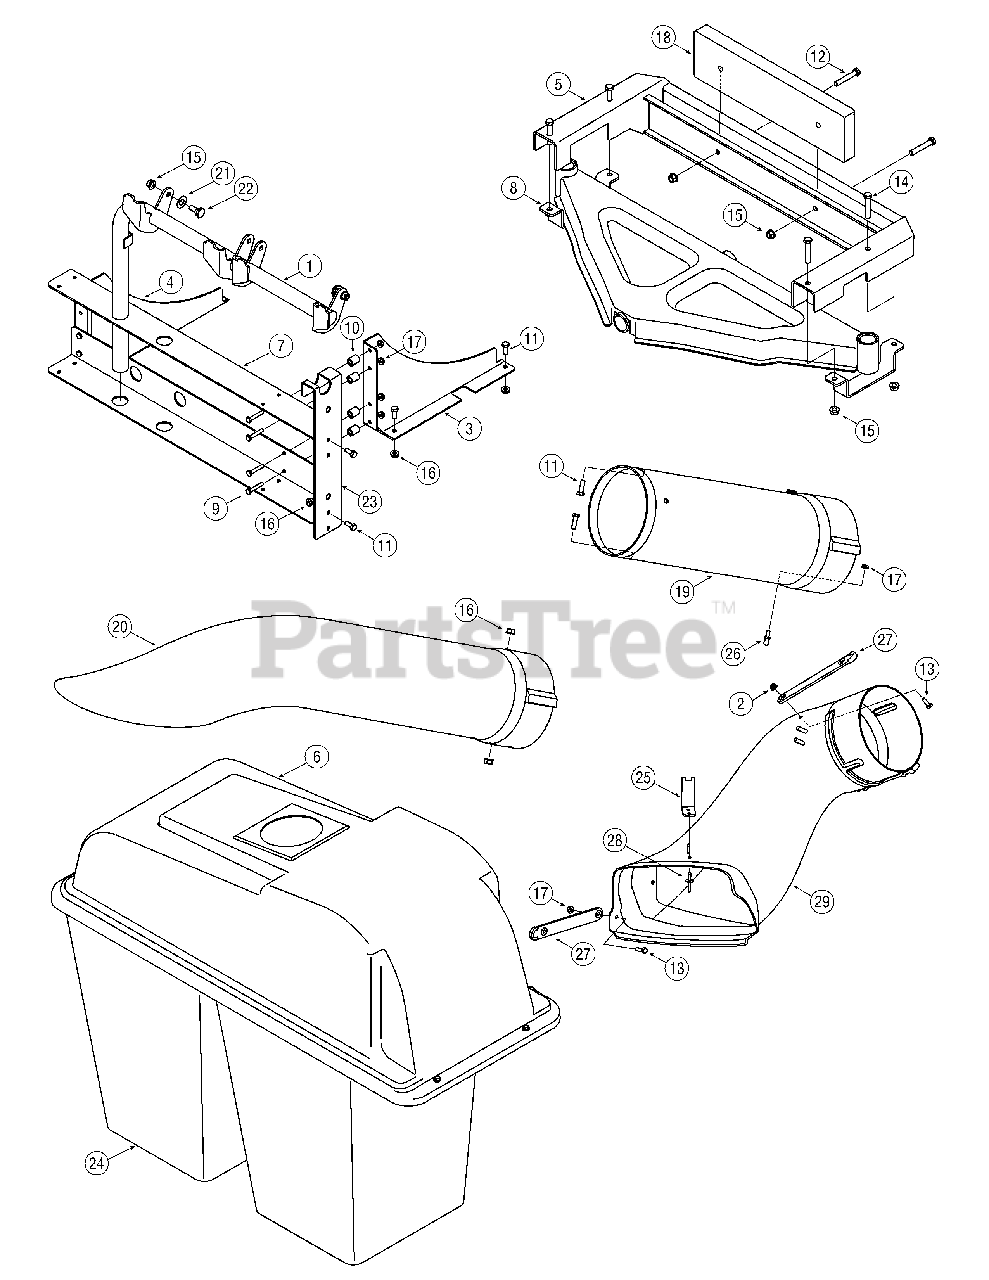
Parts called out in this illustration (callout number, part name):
2	Flange Lock Nut 1/4-20
3	Mounting Assembly RH
6	Grasscatcher Cover Assembly
9	Hex Bolt 1/4-20 x 1.50
10	Spacer .325 x .625 x .770 LG
11	Hex Bolt 5/16-18 x 1.00
12	Hex Bolt 3/8-16 x 2.25
13	Hex Bolt 1/4-20 x 1.25
14	Hex Bolt 3/8-16 x 2.0
15	Top Lock Flange Nut 3/8-16
16	Flange Lock Nut 5/16-18
17	Flange Lock Nut 1/4-20
18	Weight Bar
19	Chute Extension
20	Chute Tube
21	Bell Washer
22	Shoulder Screw
24	Grass Bag Assembly
24	Screw, #10-24 x .5
24	Hex Sems Nut, 10-24
24	Bag
24	Self Tapping Screw, 5/16-18 x .625
26	Grasscatcher Pin
27	Chute Strap
28	Rivet .187 Dia. #66
29	Chute Elbow
